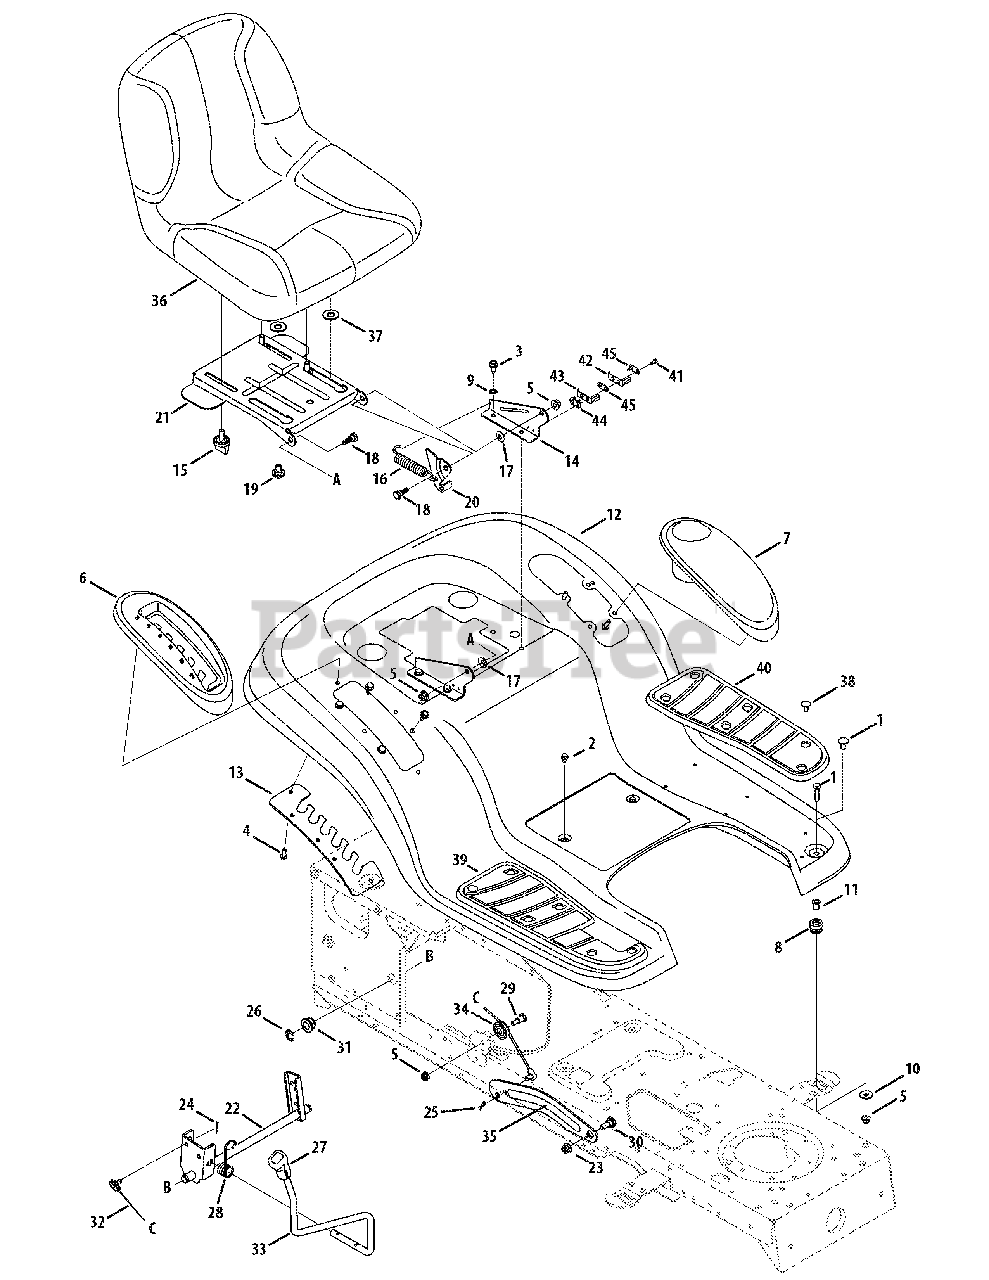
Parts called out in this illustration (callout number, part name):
1	Hex Screw, 5/16-18 x 1.25
1	Carriage Bolt, 5/16-18
2	Screw, 1/4-20, 0.500
3	Screw, 5/16-18, 0.750x
4	Screw, 1/4-15, 0.750
5	Nut, Flange Lock, 5/16-18, GrF
6	Deck Lift Lever Cover
7	Cover with Cup Holder
8	Grommet, .4375 x .750
9	Lock Washer, 5/16
10	Washer, Flat,.344 x 1.0 x.063
11	Flanged Spacer
15	Knob, 3/8-16
16	Spring, Extension,.84 Dia. x 4.6
17	Wash, Flat, .340 x .688 x .065
18	Screw, Shoulder,.437 x.268
19	Shoulder Screw
20	Seat Bracket, Lift
24	Pin, Cotter,.072 Dia. x 1.13
25	Pin, Cotter, 3/32, 1.0
26	Ring, E Type,.625 Dia.
27	Grip, Handle, 1/2
28	Spring, Torsion
29	Screw, 5/16-18 x.620 Gr2
30	Scr.,Shldr, .625 x.165,
30	Scr.,Shldr, .500 x.270,
31	Bearing, Hex Flange
32	Cable, Lift, 16.16
33	Handle, Lift
34	Pulley, Roller
36	High Back Seat
37	Flat Washer, .406 x .875 x .059
38	Ratchet Clip
39	RH Foot Pad,Rubber
40	LH Foot Pad, Rubber
41	Screw, #8-18 x.50
42	Spring Switch, Outer
43	Spring Switch, Inner
44	Plate, Insulator Boss
45	Plate, Insulator
